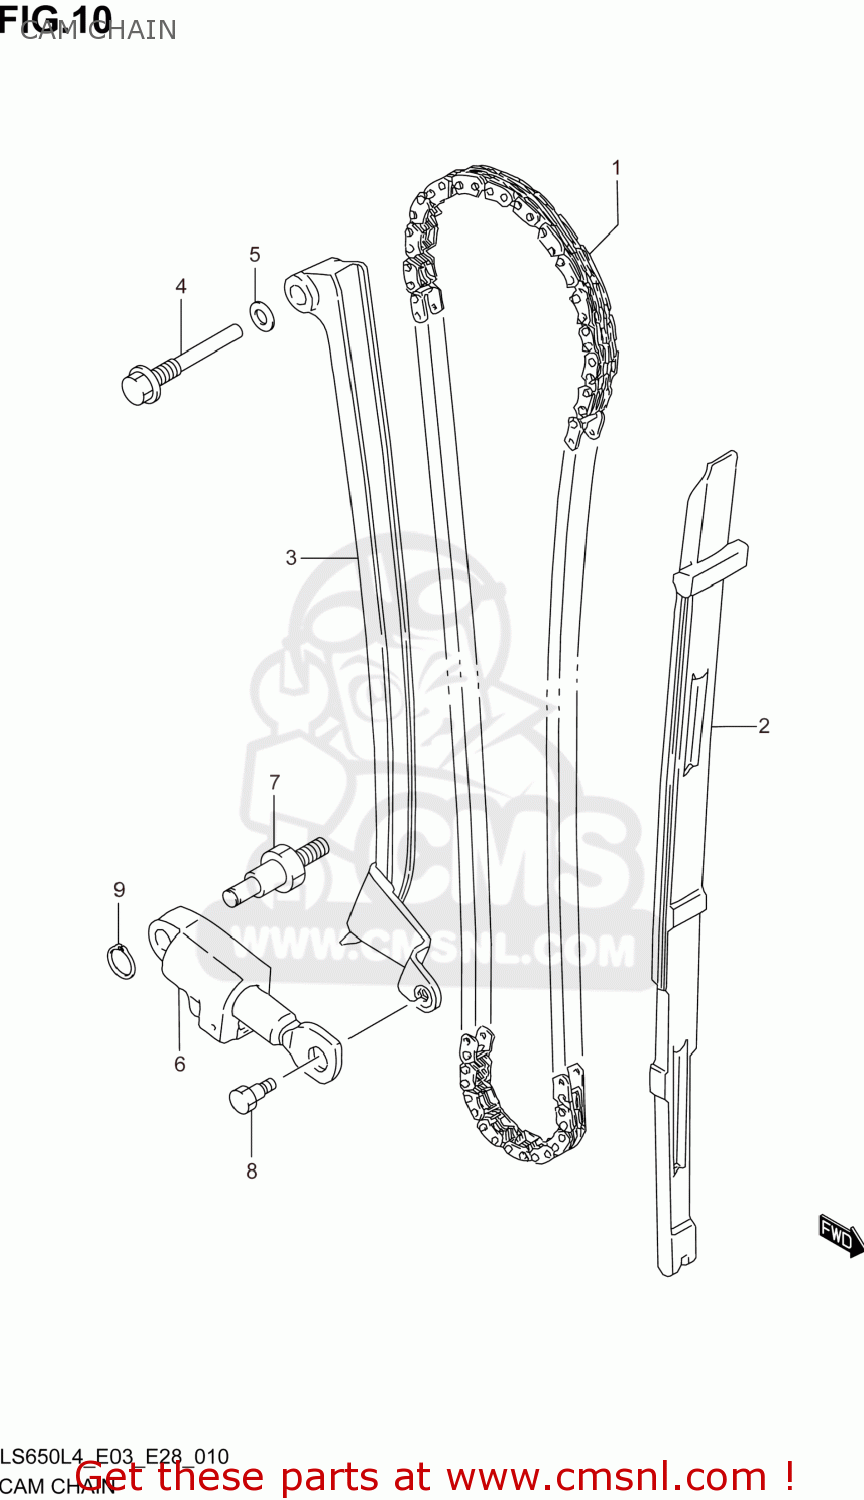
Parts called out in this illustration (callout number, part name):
1	CHAIN,CAMSHAFT DRIVE
2	GUIDE,CAM CHAIN
3	TENSIONER,CAM CHAIN
4	BOLT,CAM CHAIN TENSIONER
5	GASKET(8.2X14X1) (NAS)
6	ADJUSTER ASSY,TENSIONER
7	BOLT,STUD
8	BOLT
9	CIRCLIP
